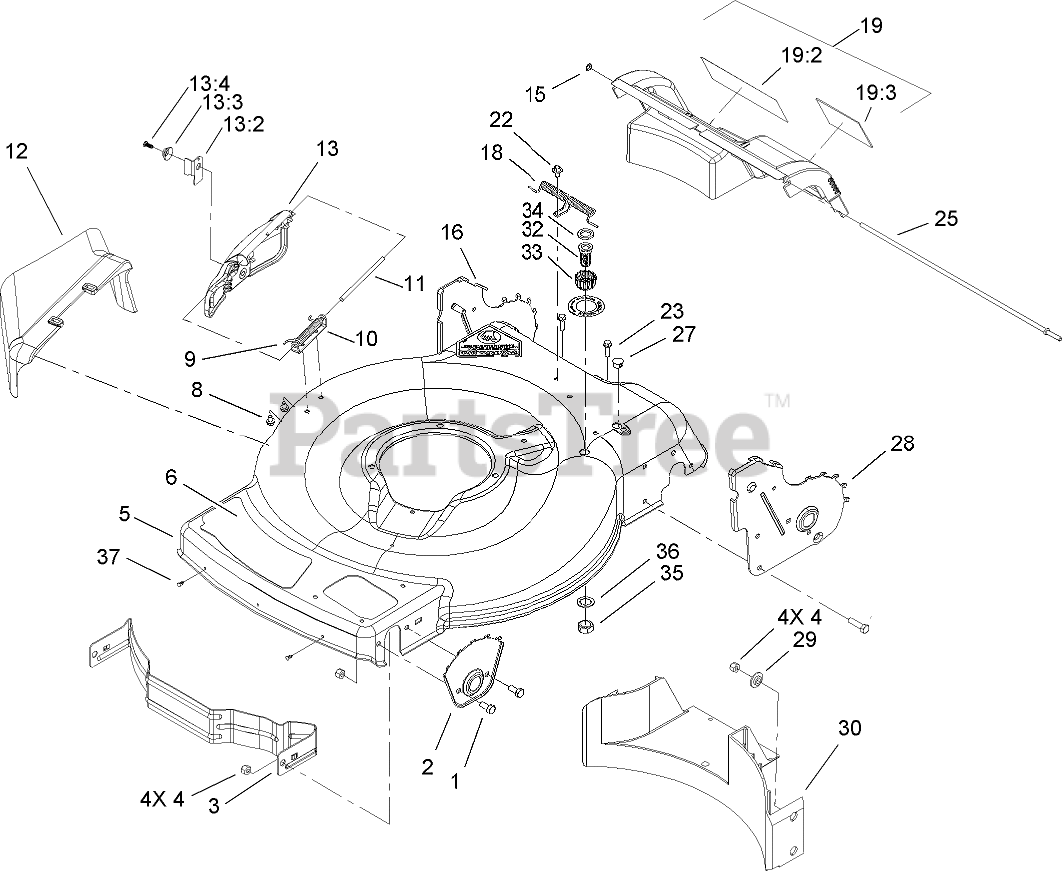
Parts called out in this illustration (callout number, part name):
1	SCREW-HH
2	Plate-HOC, Front
3	Baffle-Front
4	NUT-LOCK, NI
5	HOUSING ASM
6	DECAL-DECK
8	SCREW-HWH
9	SPRING-TORSION
10	BRACKET-COVER
11	ROD-COVER
12	CHUTE-DISCHARGE, SIDE
13	DISCHARGE DOOR ASM
13:2	LATCH-DOOR
13:3	CAP-DOOR
13:4	SCREW-PLASTITE
15	NUT-PUSH
16	11 INCH RH HOC PLATE ASM
18	Spring-Door, Rear
19	REAR DOOR ASM
19:2	DECAL-WARNING
19:3	DECAL-WARNING
22	SCREW AND WASHER ASM
23	SCREW-HWH
25	Rod-Pivot, Rear Door
27	Plug-Dome
28	11 INCH LH HOC PLATE ASM
29	Washer-Stepped
30	Baffle-Rear
32	PORT-WASHOUT
33	COUPLING-HOSE, WASHOUT PORT
34	WASHER-SEAL, WASHOUT PORT
35	NUT-JAM
36	WASHER-TOOTH, INTERNAL
37	PLUG-ARROW
